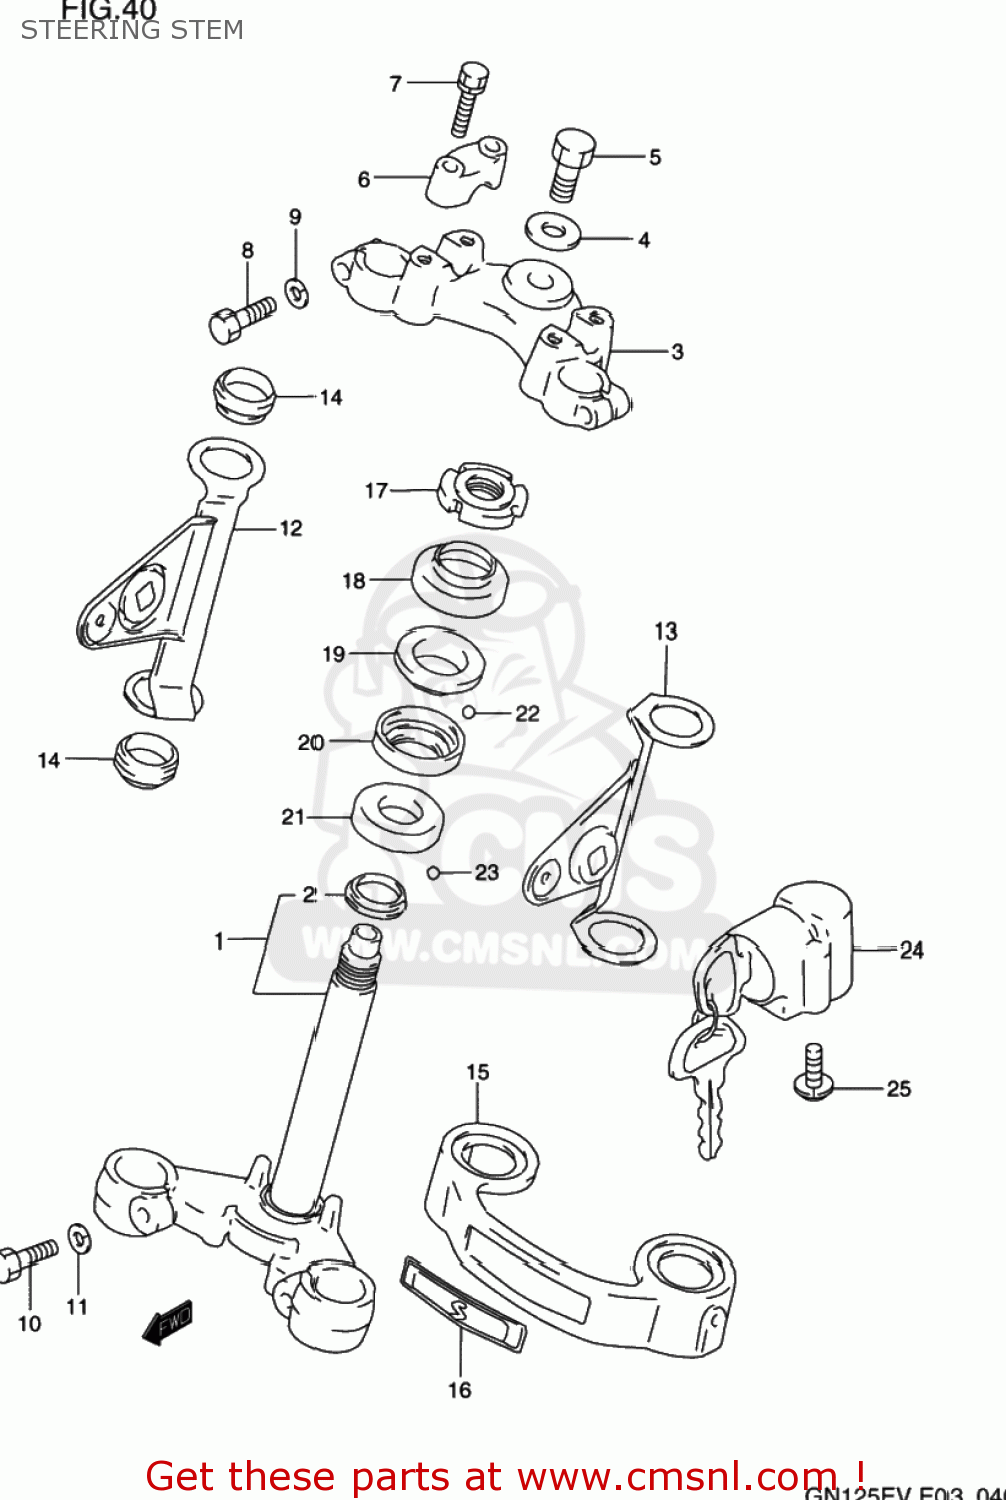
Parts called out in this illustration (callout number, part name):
1	STEM,STEERING
2	RACE,STEERING OUTER LWR
3	HEAD,STEERING STEM(BLACK)
4	WASHER,STEM HEAD(10.5X30X3.2)
5	BOLT,FR FORK(10X33)
6	HOLDER,HANDLE(BLACK)
7	BOLT
8	BOLT
9	WASHER,LOCK
10	BOLT,FR FORK LWR(12X33)
11	WASHER,LOCK
12	BRACKET,HEADLAMP,R
13	BRACKET,HEADLAMP,L
14	CUSHION,HEADLAMP BRACKET
15	COVER,FR FORK
16	EMBLEM,FR FORK COVER
17	NUT,STEERING STEM(25X44X10)
18	DUST SEAL,STEERING UPR
19	RACE,STEERING OUTER UPR
20	RACE,STEERING INNER UPR
21	LACE,STEERING INNER LWR
22	BALL
23	BALL
24	LOCK ASSY,STEERING
25	SCREW
